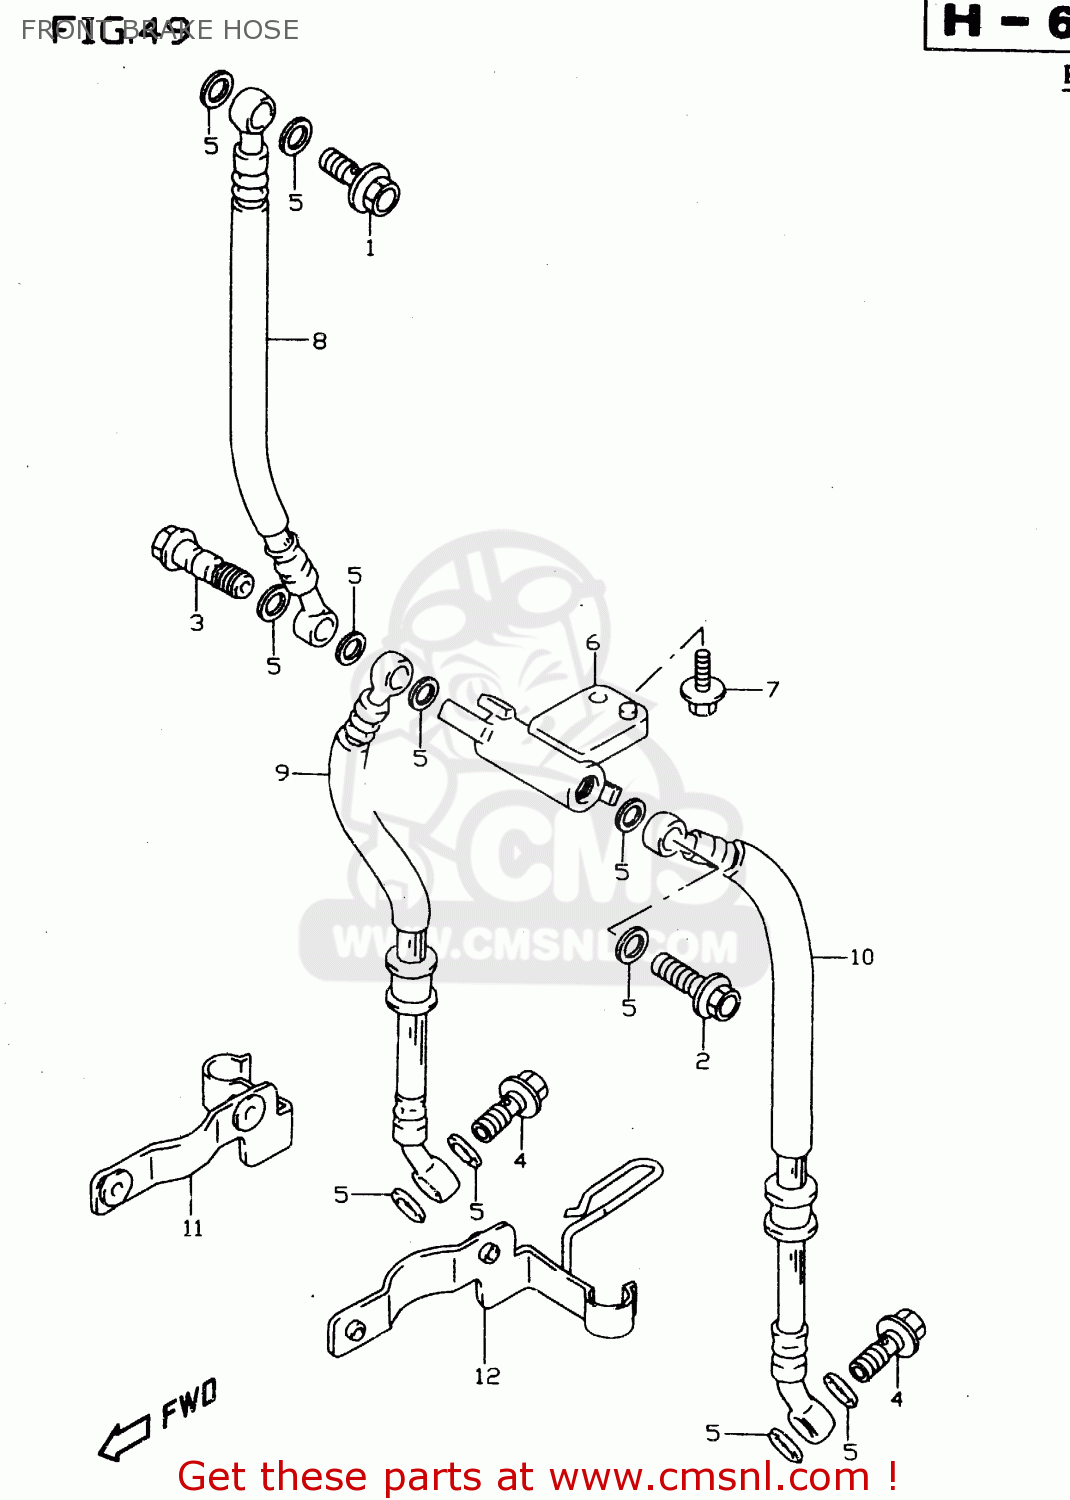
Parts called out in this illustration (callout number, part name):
1	BOLT UNION
2	BOLT UNION
3	BOLT UNION
4	BOLT UNION
5	WASHER(10X15X1.5)
6	JOINT,BRAKE HOSE
7	BOLT
8	HOSE,FR BRAKE NO.1
9	HOSE, FRONT BRAKE NO.2 RH
10	HOSE, FRONT BRAKE NO.2 LH
11	CLAMP,FR BRAKE HOSE NO.2,R
12	CLAMP,FR BRAKE HOSE NO.2,L
